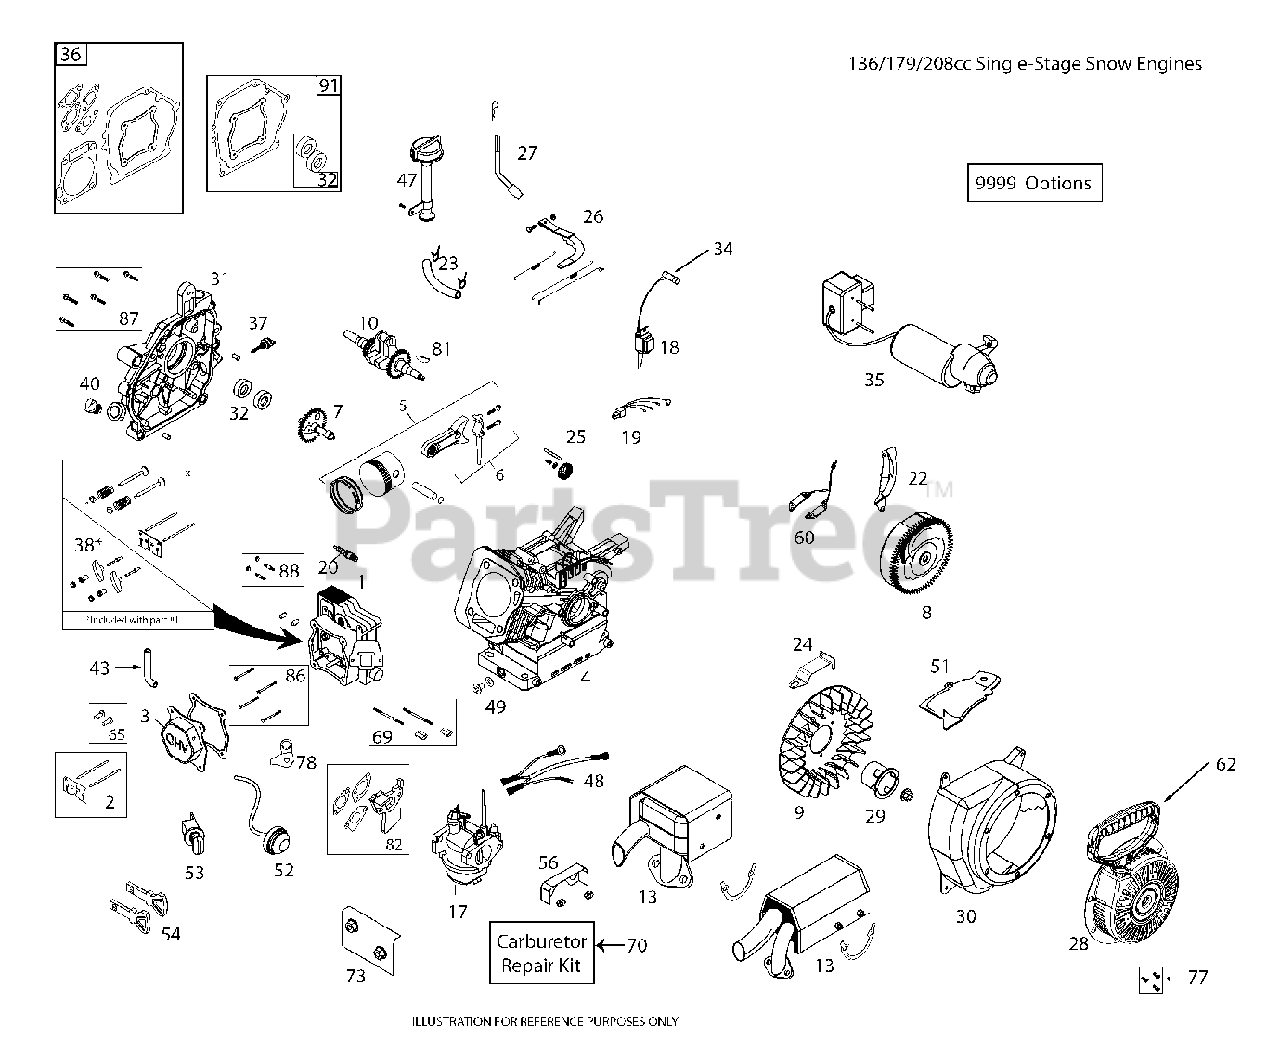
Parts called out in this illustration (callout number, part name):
1	CYLINDER HEAD ASSY.LCT.208
2	KIT.PUSH.ROD.SRV(SK208-1001)
3	VALVE COVER ASSEMBLY
4	Poulan TBD
6	Poulan TBD
8	FLYWHL.ASSY.MANUL.SK2081700
9	KIT.COOLNG.FAN.SERV(SK208-4000
10	CRANKSHAFT KEYED LCT 179
13	MUFFLER.ASM.LCT.208CC.SS
17	CARB.ASM.SS/SNO.LCT(SKSNO313)
18	208CC IGN COIL (STD)
19	Poulan TBD
20	SPARK.PLUG(2083810)
22	SHIELD.FLYWHEEL.ELEC.STRT.208C
23	KIT.FUEL.HOSE.208CC.SING/STAGE
24	SPEED.CTRL.BRKT.(SKSN0150)
25	GOVENOR.GEARS ASM(SK2082900)
26	CARBURETTOR GOVERNOR LINK.ASM.
27	KIT.GOVERNOR.CRANK(SK208-3100)
28	STARTER.RECOIL.S/S SNO.78".ROP
29	STRTER.CUP(NON-SLOT)SKSN0601.2
30	BLOW.HSG.ASSY.ELEC(SKSN-0612)
31	COVER CRANKCASE.LCT.SK2083605
32	SEAL KIT (2 PCS)
34	SPARK.PLUG.BOOT.SNW,SKSN4691.1
35	Poulan TBD
36	GASKET.KIT.208CC(SK2084300.1)
37	DIPSTICK SMALL
38	ROCKER ARM KIT
40	NON REMOVABLE PLUG
43	TUBE.BREATHER.LCT.208
47	TUBE HIGH OIL FILL LCT 179
48	HARNESS.WIRE.SINGLE.STAGE.LCT
49	KIT.OIL.DRAIN.PLUG(SK2089911
52	BULB.FUEL.PRMR.W/HOSE(SKSNO306
53	SWITH.KEY.ASSEM.SNOW.SINGLE.ST
54	KEY SET(2 KEYS) SKSN0407.1
56	SHIELD.VAPOR.SNOW
60	Poulan TBD
62	STARTER.GRIP.SNOW.LCT.SKSN0603
65	TAPPET.KIT.LCT.208CC
69	CARB.STUDS & COUPLING KIT.SNOW
70	CARB.REPAIR.KIT.LCT.SK9900.1
73	Poulan TBD
77	BOLT.KIT.RECOIL.LCT.ALL.ENGINE
81	KEYS.FLYWHEEL.208/414CC.5PACK
82	SPACER.CARBURETOR.208CC.LCT
86	KIT.BOLT.CYLINDER.HEAD.(4PC)
87	KIT.BOLT.CRANKCASE.COVER.6PC
88	STUD.MUFFLER.KIT.LCT
91	Crankcase Cover Gasket
9999	High Altitude Jet for Beyond 6,000 Feet
